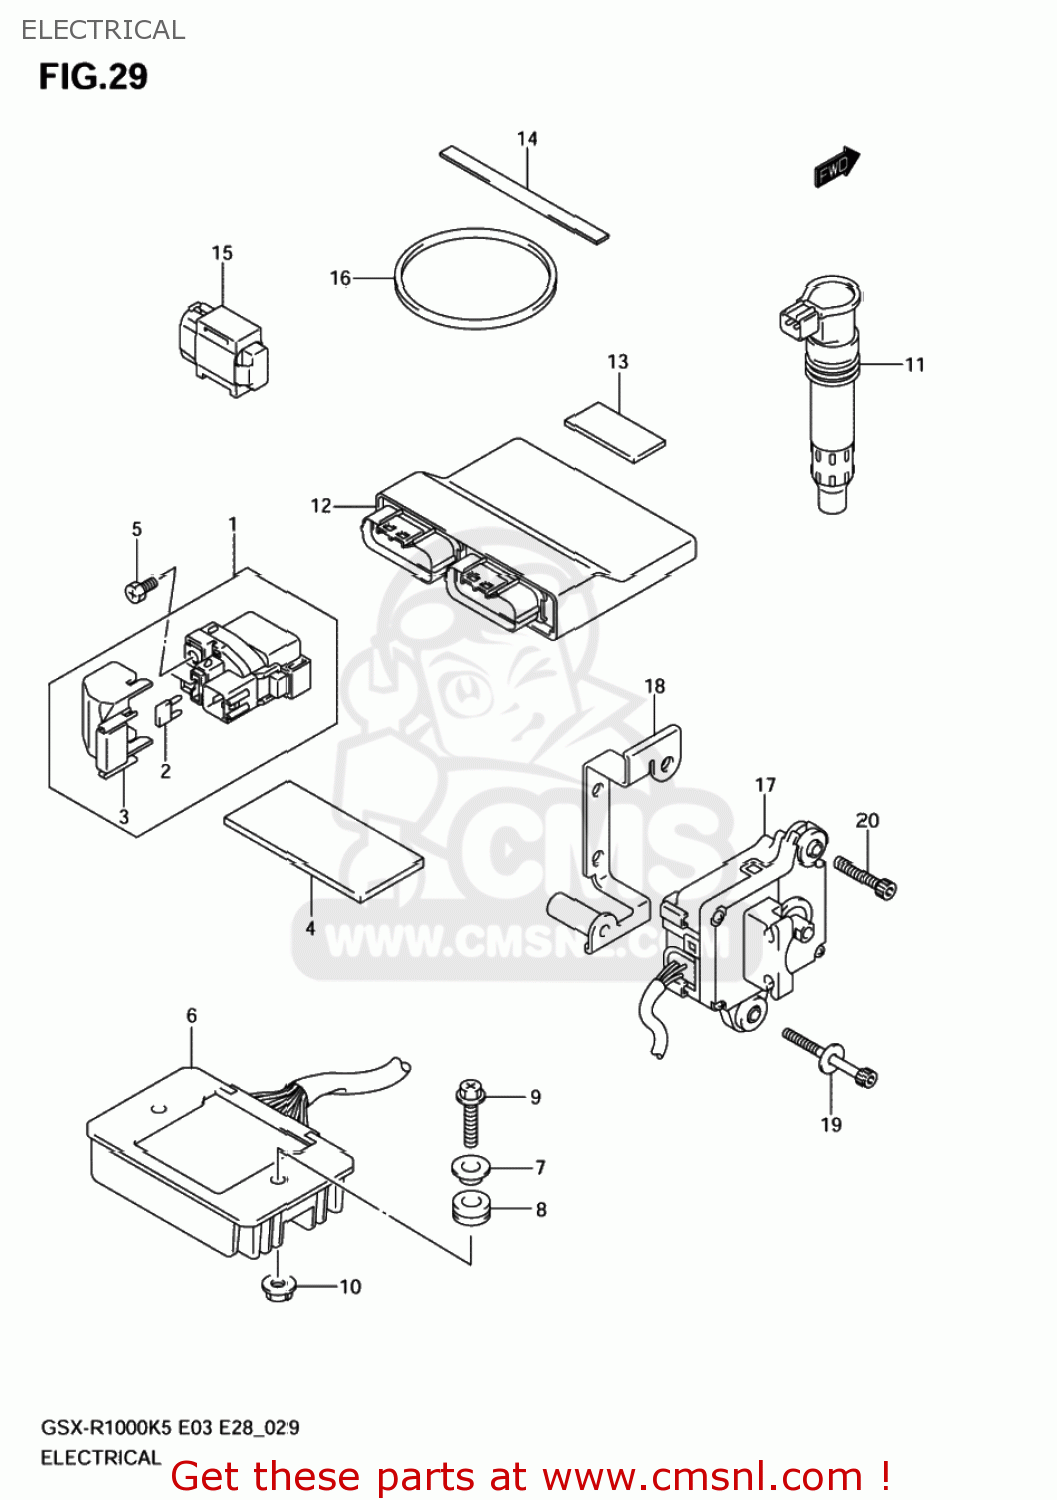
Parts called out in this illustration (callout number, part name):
1	RELAY ASSY,STARTING MOTOR
2	COVER
3	FUSE(30A)
4	CUSHION,FUEL TANK
5	SCREW(6X8)
6	RECTIFIER ASSY
7	SPACER(6.2X8.4X6.9)
8	CUSHION
9	SCREW
10	NUT
11	COIL ASSY,IGNITION
12	CONTROL UNIT,F
13	PROTECTOR(170X95X3.0)
14	CUSHION(130X10X2)
15	SENSOR ASSY,FUEL CUT
16	O RING(D:3.5,ID:61)
17	ACTUATOR ASSY,EXHAUST CONTROL
18	HOLDER,ACTUATOR
19	BOLT(6X60)
20	BOLT
